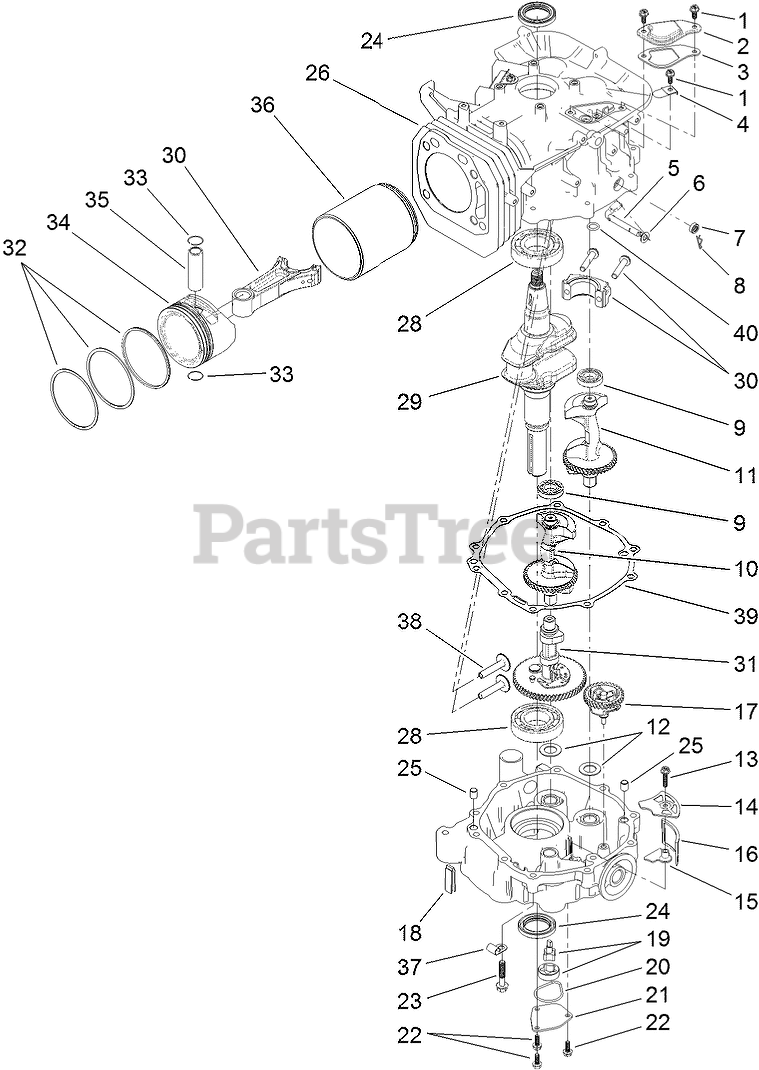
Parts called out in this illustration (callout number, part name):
1	SCREW-HHF
2	PLATE-BREATHER
3	GASKET-BREATHER
4	VALVE-REED
5	GOVERNOR-SHAFT
6	WASHER-PLAIN
7	SEAL-OIL
8	PIN-HAIR
9	BEARING-BALL
10	BALANCER-RH
11	BALANCER-LH
12	WASHER
13	SCREW-HHF
14	COVER-STRAINER, OIL
15	PLATE-BAFFLE, OIL
16	STRAINER-OIL
17	GOVERNOR ASM
18	DEFLECTOR-OIL, RUBBER
19	PUMP-OIL
20	SEAL-PUMP, OIL
21	COVER-PUMP, OIL
22	SCREW-HHF
23	SCREW-HHF
24	SEAL-OIL
25	PIN-DOWEL
26	CRANKCASE ASM (W/BEARINGS)
28	BEARING-BALL
29	CRANKSHAFT
30	CONNECTING ROD ASM
31	CAMSHAFT
32	RING SET
33	RING-RETAINING, PISTON PIN
34	PISTON
35	PIN-PISTON
36	CYLINDER ASM
37	CLAMP-J
38	LIFTER-VALVE
39	GASKET-CRANKCASE
40	O-RING
